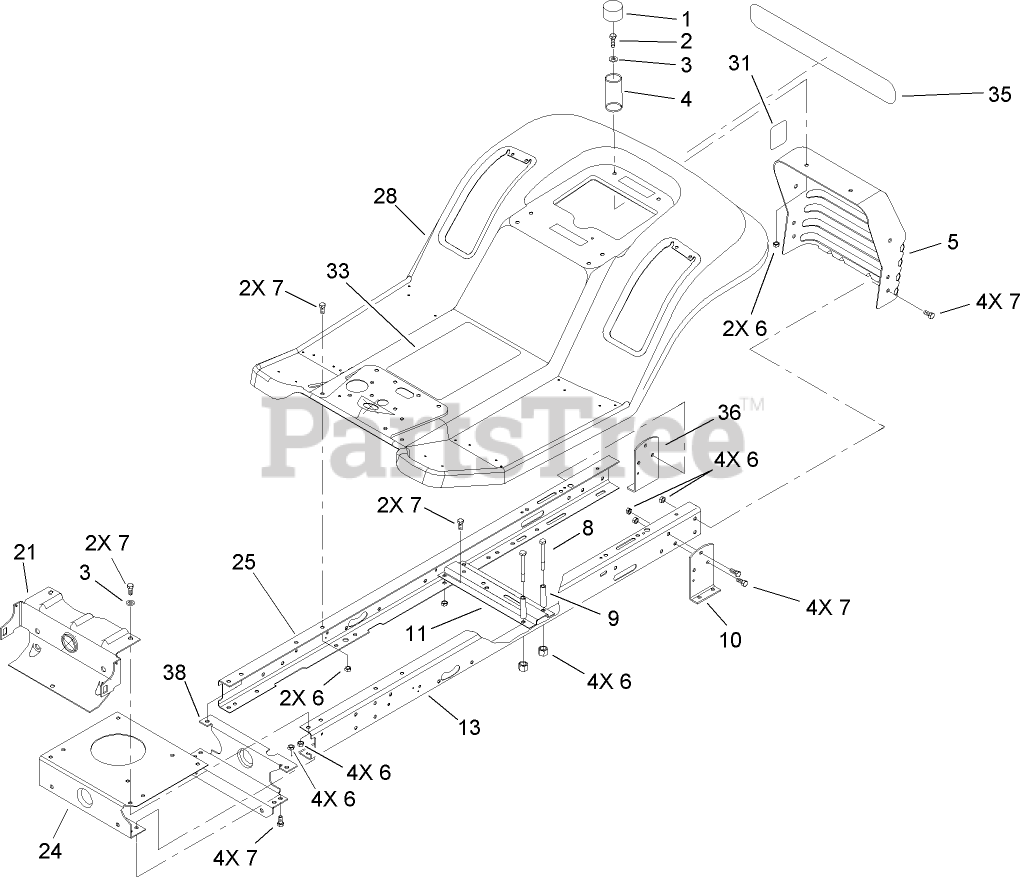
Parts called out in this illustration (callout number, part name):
1	CAP-PROTECTOR
2	SCREW-HH
3	WASHER-PLAIN
4	SPRING-COMPRESSION
5	SUPPORT-SEAT/REAR HITCH
6	NUT-LOCK, NI
7	SCREW-HH
8	SCREW-HH
9	SPACER
10	BRACKET-MOUNTING, LH TRANSAXLE
11	BRACKET-IDLER PIVOT
13	RAIL-FRAME, LH
21	SUPPORT-AXLE, FRONT
24	PLATE-MOUNTING, ENGINE
25	RAIL-FRAME, RH
28	REAR BODY ASM
31	DECAL-VALVE, DUMP
33	DECAL-INSTRUCTION, HYDRO
35	DECAL-REAR FENDER, LAWN TRACTORS
36	BRACKET-MOUNTING, RH TRANSAXLE
38	SUPPORT-REAR
